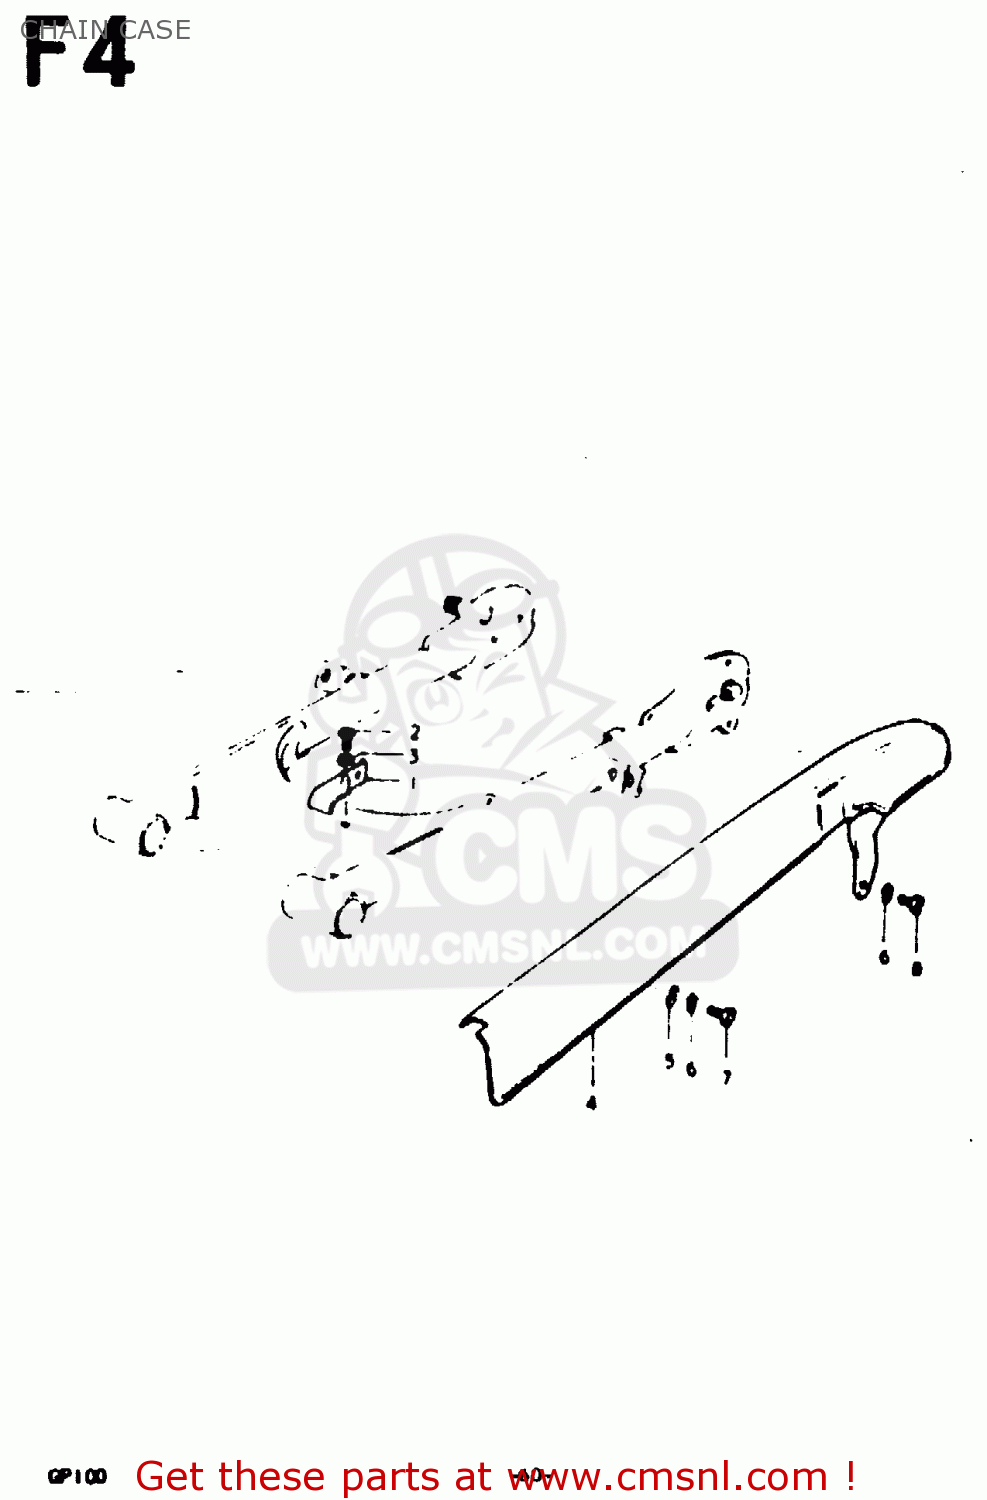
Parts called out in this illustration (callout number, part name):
1	BRACKET, CHAIN CASE FRONT
2	SCREW
3	LOCK WASHER
4	CHAIN CASE
5	WASHER
6	LOCK WASHER
7	BOLT
8	BOLT
